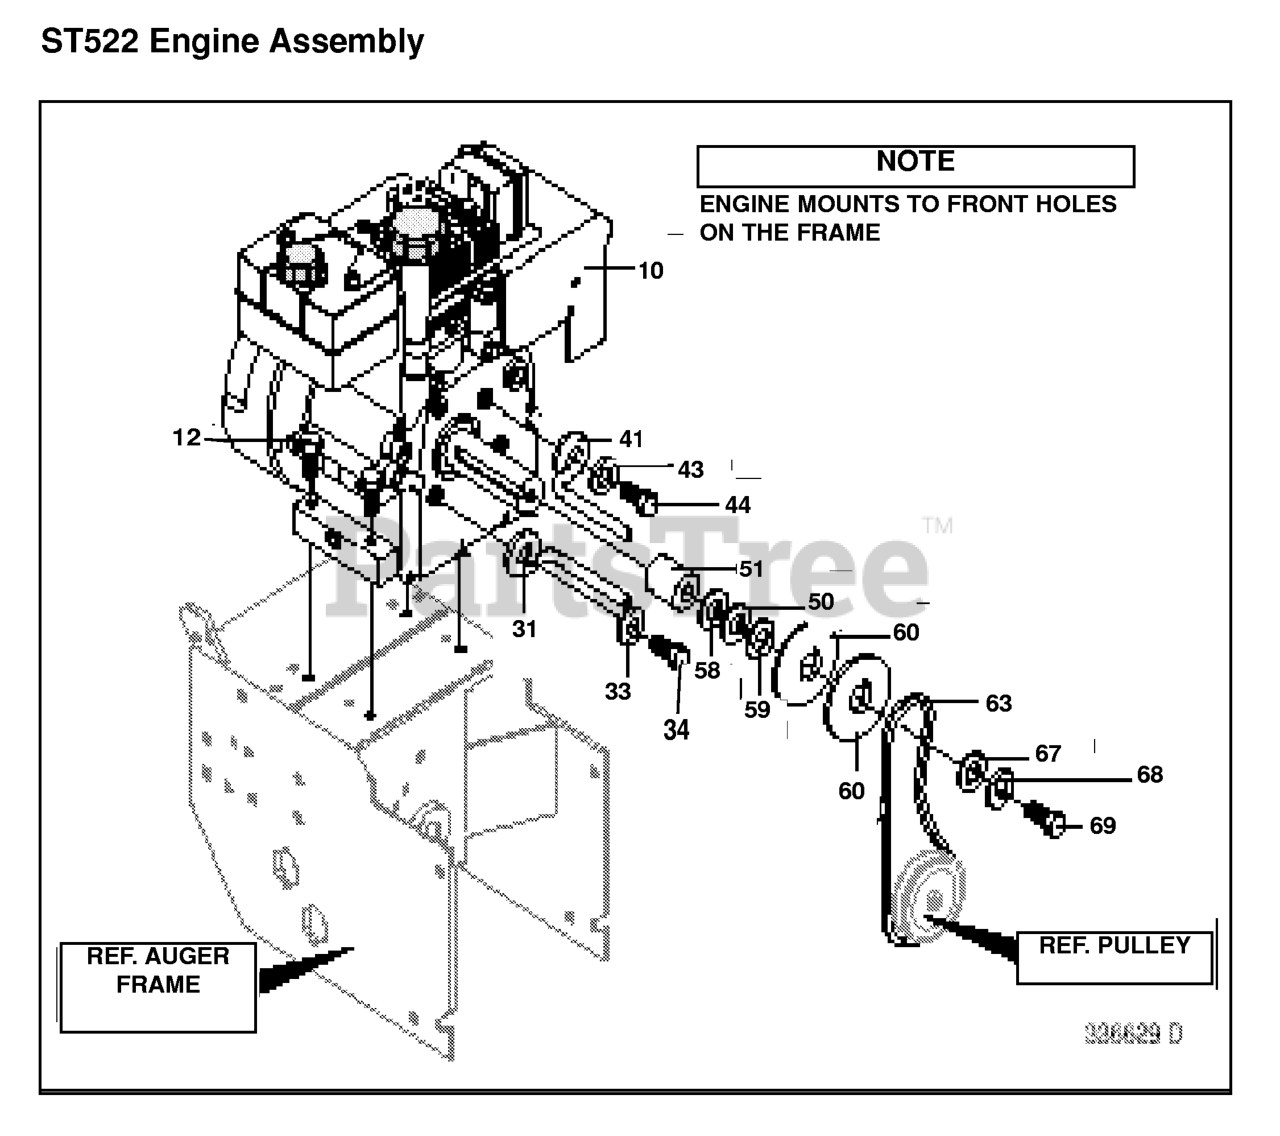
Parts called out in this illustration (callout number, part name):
12	SCREW, 5/16-18
31	BELT GUIDE
33	WASHER, HVSPTLK .328X.60X
41	BELT GUIDE
43	WASHER, HVSPTLK .328X.60X
51	SPACER, SLEV
59	Spacer, Slev .753 x 1.12 x .38
60	PULLEY, ENGINE
68	WASHER, REGSPTLK.393X.68X
69	SCREW, 3/8-24X1.00 NYLHHC
